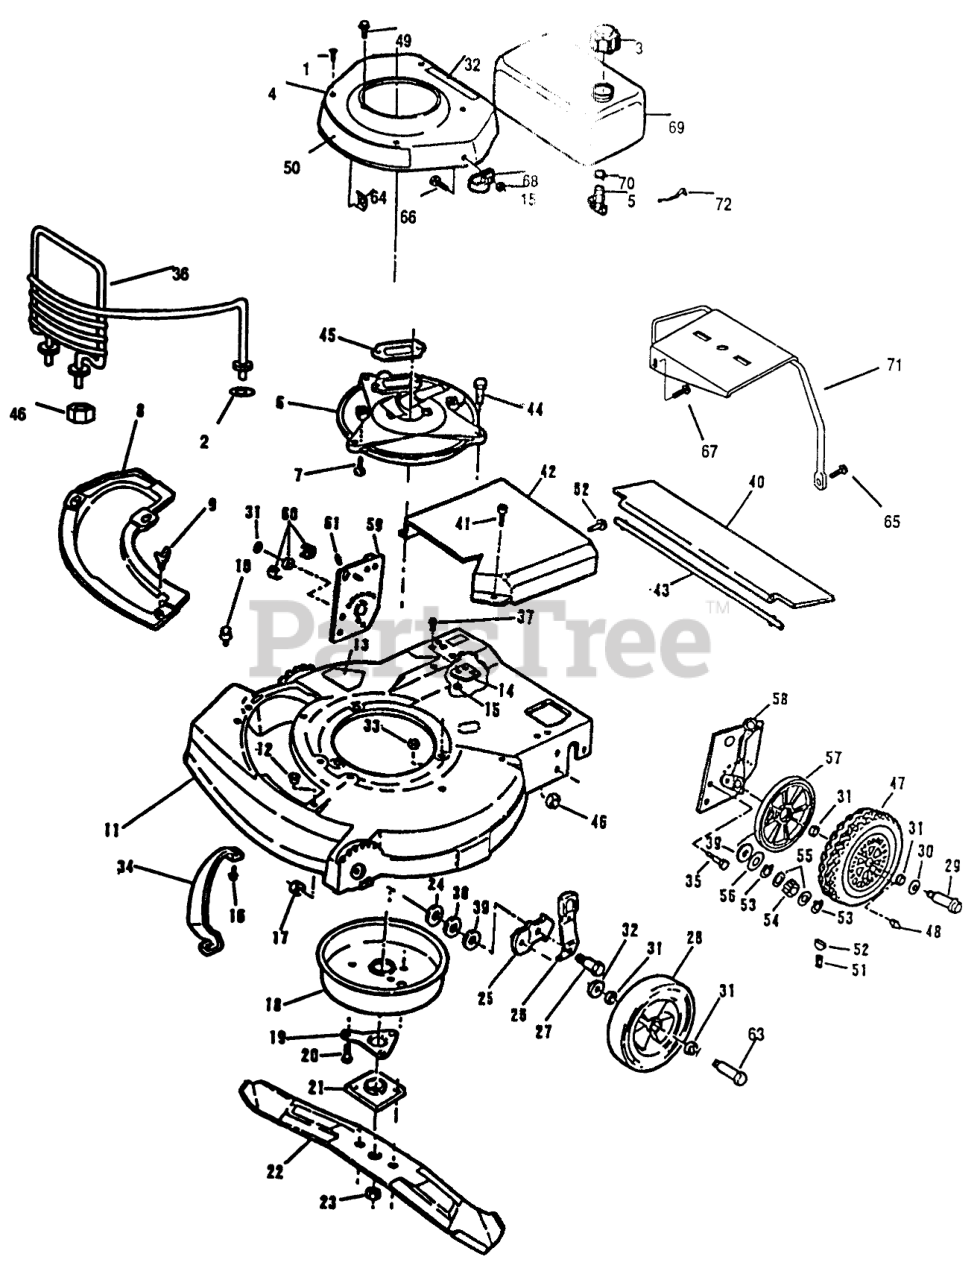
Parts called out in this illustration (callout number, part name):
1	SCREW S
2	WASHER
3	FUEL CAP & INSERT
4	SHROUD AY B S
5	VALVE&SCREEN SM
6	PLATE F
7	SCREW V
8	CoverPlate
9	WING SCREW LAWRE
10	Bolt
11	Housing Assembly
12	Grommet
13	Decal
14	BOLSTER
15	LOCKNUT E
16	Screw
17	Nut
18	MUFFLER COVER F
19	SUPPORT F
20	SCREW
21	PLATE AND COLLAR ASM
22	21" Blade
23	NUT-BLADE
24	WASHER
25	Bracket
26	SPRING ARM ASM
27	BOLT
28	WHEEL AND TIRE ASM
29	BOLT WHEEL
30	WASHER-PLAIN
31	WASHER
32	DECAL S
33	NUT-LOCK F
34	BAR-TOE
35	Hex Hd. Screw
36	SCREW S
37	Screw
38	WASHER
39	WASHER
40	SHIELD-TRAILING
41	SCREW SEMS TRM HEX HD
42	COVER DRIVE PL
43	ROD-TRAILING SHIELD
44	SCREW-HH
45	Gasket
46	NUT-LOCK F
47	WHEEL,TIRE&BRG AY
48	FITTING LINCOLN
49	SCREW SEMS SM
50	APPLIQUE S
51	SPRING
52	KEY
53	RET RING
54	PINION BROCKWAY
55	SPACER/GR ALGHNY
56	THRUST WASHER
57	COVER-WHEEL
58	HEIGHT ADJ AY-LH
59	HEIGHT ADJ AY-RH
60	REAR AXLE BEARING
61	FITTING LINCOLN
62	SCREW
63	BOLT
64	PUSHNUT F
65	SCREW
66	Screw
67	Screw
68	CLAMP F
69	Gas Tank
70	CLAMP - HOSE S
71	BRACKET AY-TANK B
72	SPRING
